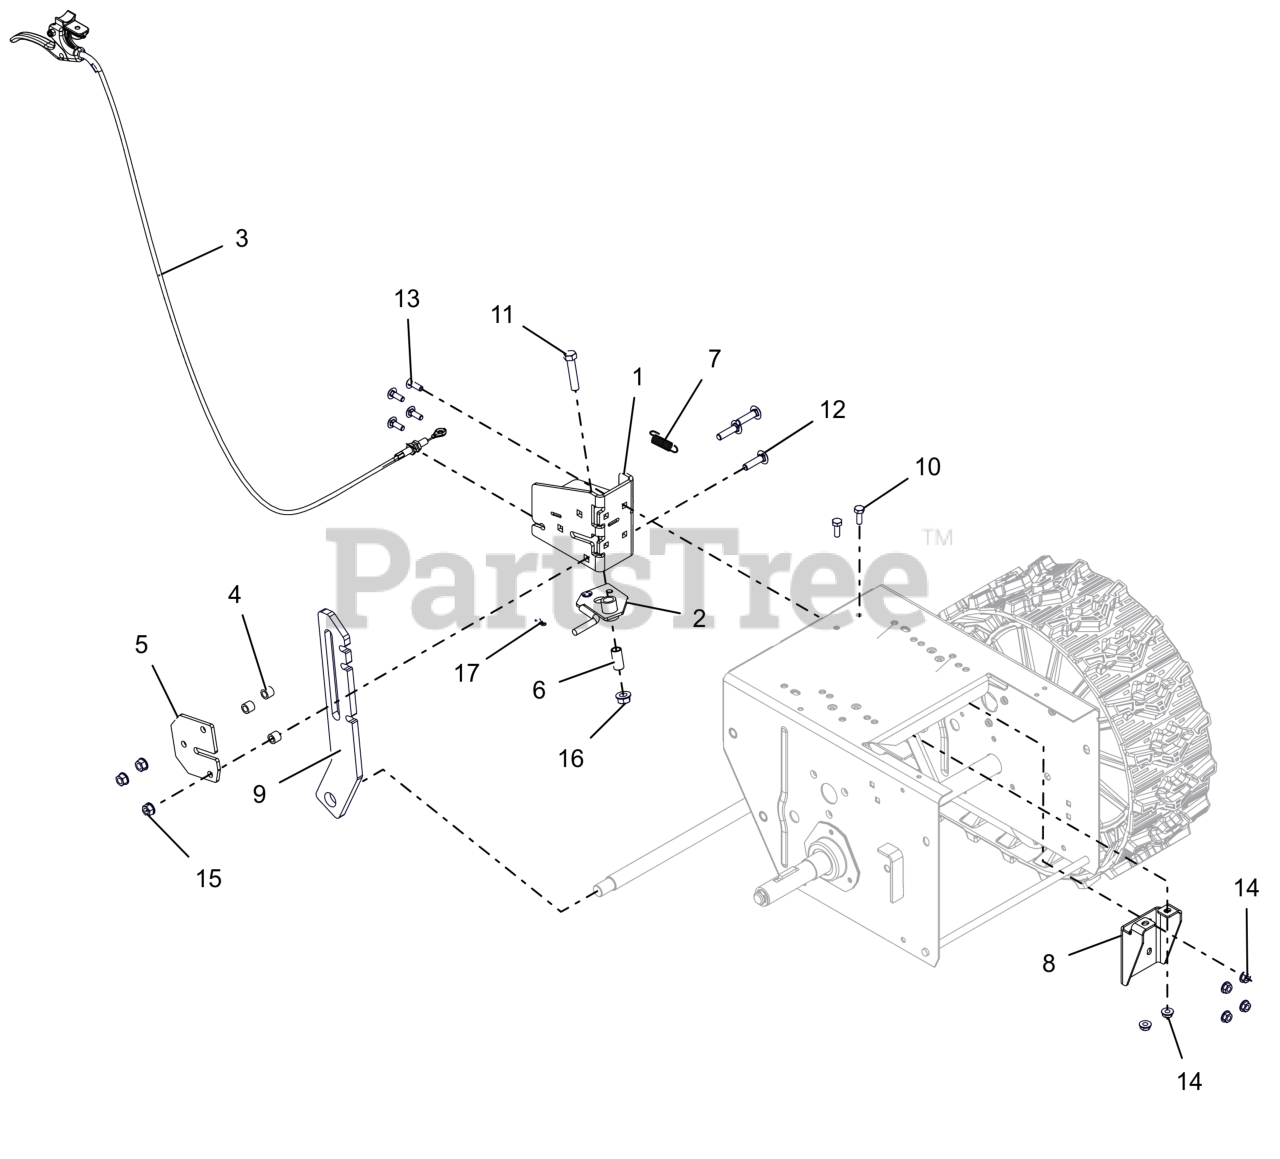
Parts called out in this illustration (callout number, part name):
1	BRACKET,HEIGHT ADJUSTER-DELUXE
2	LOCK,HEIGHT ADJUSTER TRIGGER
3	CABLE, TRACK REMOTE
4	SPACER .50 X .32 X .42
5	PLATE, HEIGHT ADJUSTER
6	BSHG-SLV .385X.500X1.045
7	SPRING-EXT .047 X .438 X 1.85
8	BRACKET, REINFORCEMENT
9	ADJUSTER, HEIGHT-DELUXE BWT
10	BLT, HEX .25-20X.75 G5 ZCC
11	BLT, HEX .38-16X1.75 G5 ZCC
12	BLT, RHSSN.31-18X1.25 G5 ZCC
13	BLT, RHSN .25-20X.750 G5 ZCC
14	NUT-LK-CTR-FLG .25-20 ZC120
15	NUT-LK-TOP-FLG .312-18 GF ZCC
16	NUT-LK-CTR-FLG .375-16 GF ZCC
17	PIN, HAIR #178 .06X.77 ZCC
